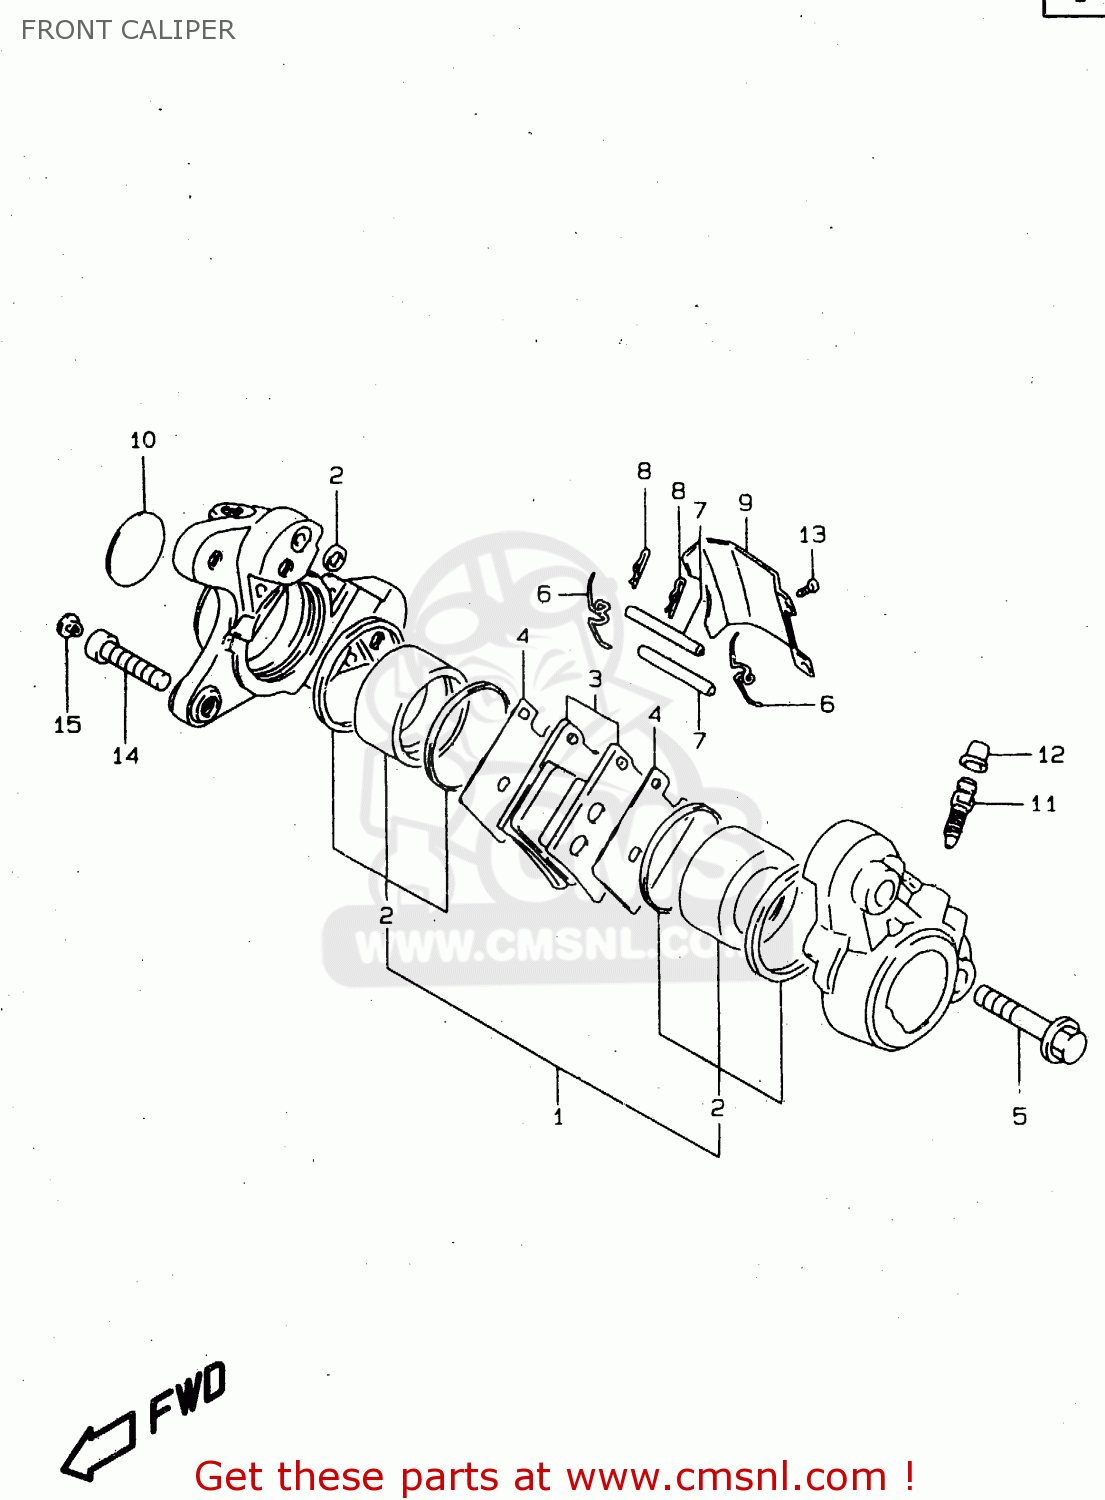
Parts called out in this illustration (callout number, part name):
1	PISTON SET
2	SEAL SET,PISTON
3	PAD SET (NAS)
4	SHIM,PAD
5	BOLT,HOUSING
6	SPRING
7	PIN,PAD
8	CLIP,PAD PIN
9	COVER,CALIPER HOUSING,DUST
10	CAP,CALIPER
11	BLEEDER
12	CAP,BLEEDER PLUG
13	SCREW,CALIPER COVER(4X6)
14	BOLT(10X33)
15	CAP(OD:12)
